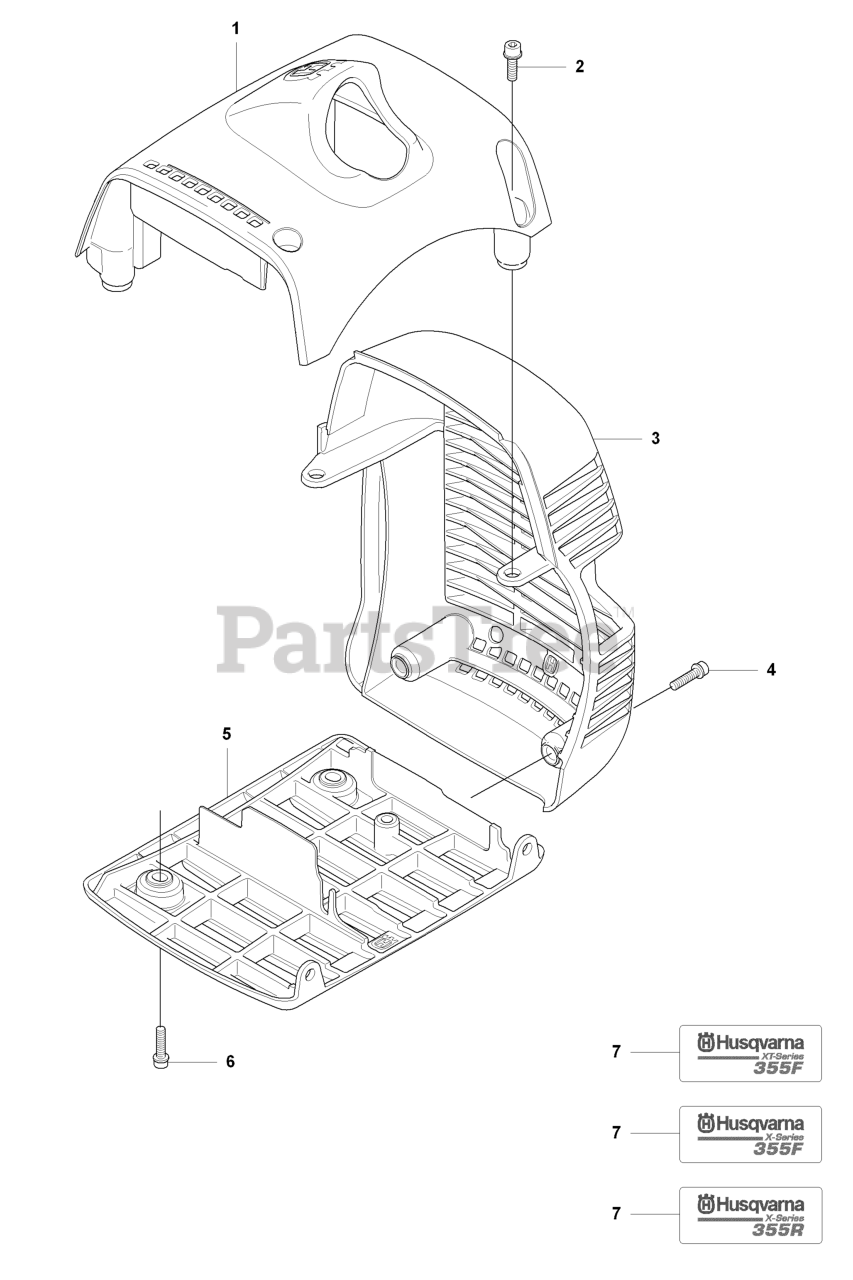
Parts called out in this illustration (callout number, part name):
1	CYLINDER COVER
3	HEAT PROTECTOR
5	PROTECTIVE COVER
7	LABEL
